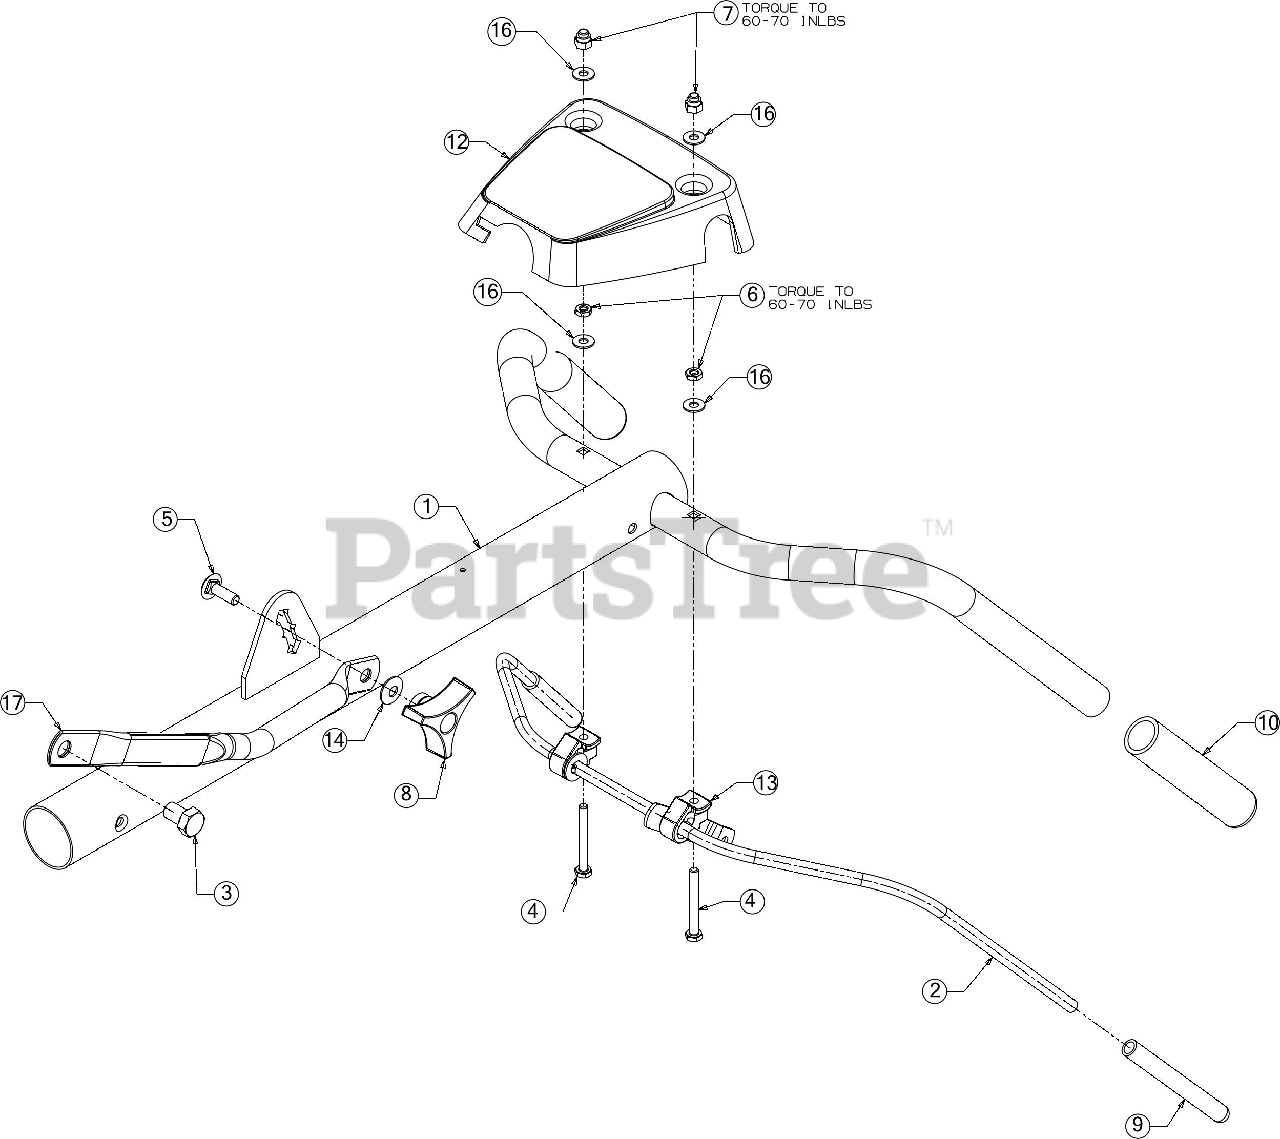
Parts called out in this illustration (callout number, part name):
1	HANDLE ASSEMBLY
2	CLUTCH HANDLE ASSEMBLY
3	BOLT 1/2-20 X .75 GR5
4	SCREW 1/4-20 X 2.25 GR5
5	SCREW 5/16-18 X 1.00
6	HEX NUT
7	HEX ACORN NUT
8	HANDLE KNOB
9	CLUTCH GRIP
12	HANDLE COVER W/O SWITCH HOLE
13	HANDLE CLUTCH HOLDER
14	BELL WASHER .337 X.867 X .057
15	FLAT WASHER
16	FLAT WASHER .271:.630:.065
17	HANDLE BRACE
